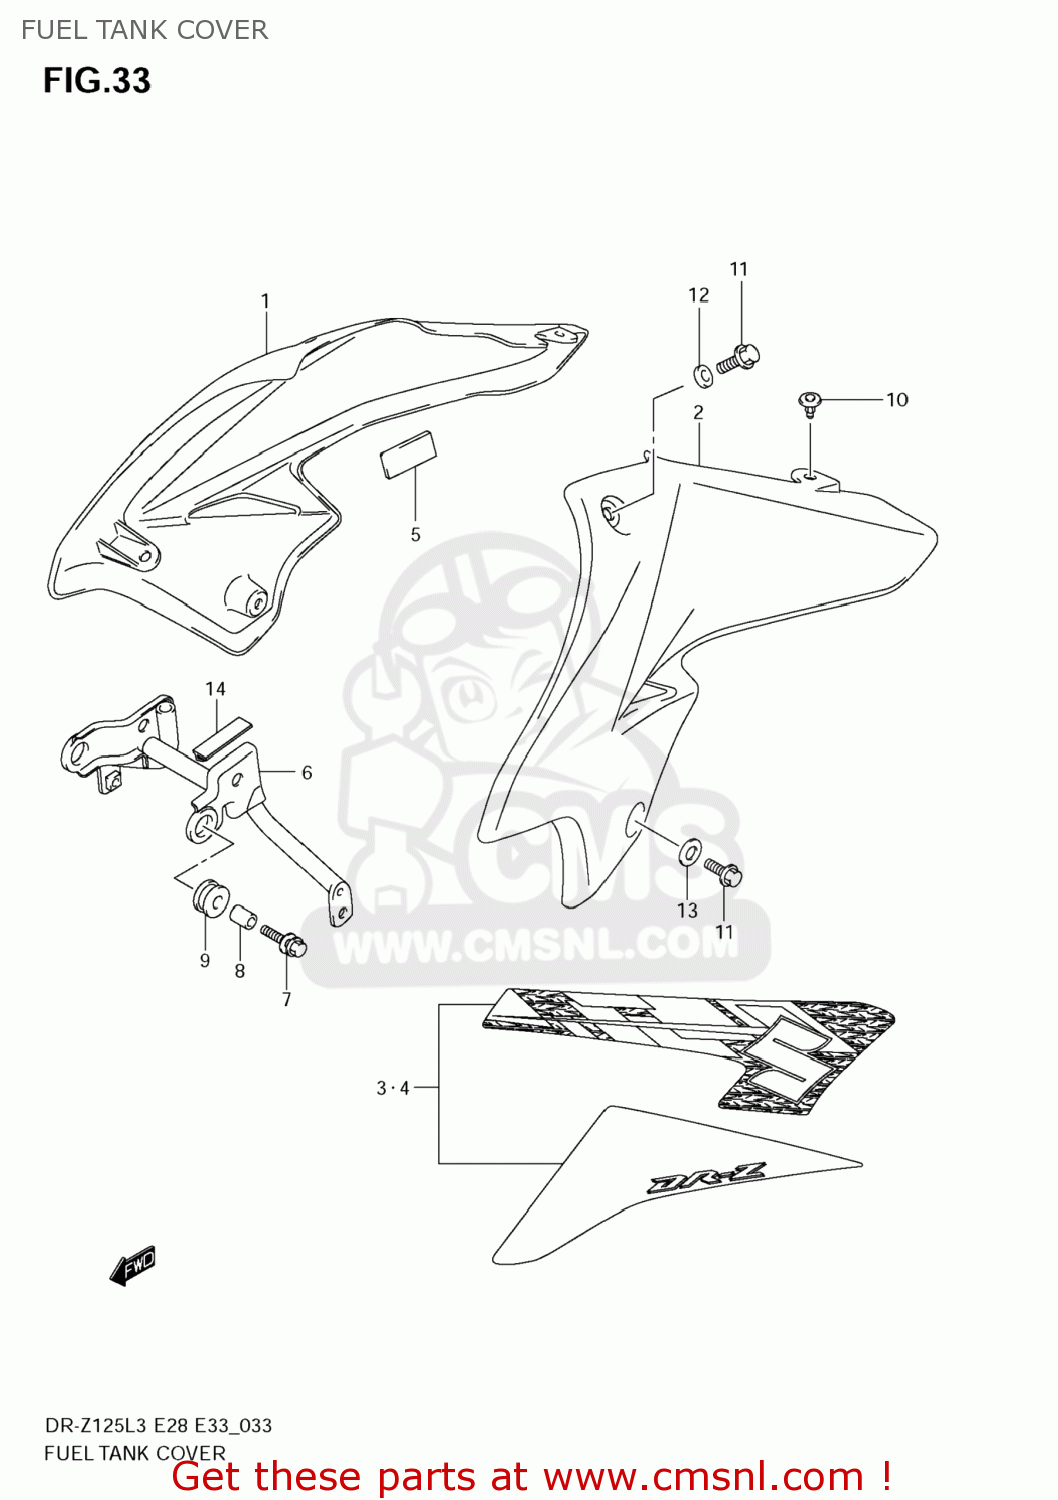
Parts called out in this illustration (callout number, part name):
1	COVER,FUEL TANK,R
2	COVER,FUEL TANK,L
3	TAPE SET,FUEL TANK COVER,R
4	TAPE SET,FUEL TANK COVER,L
5	CUSHION,FUEL TANK COVER
6	BRACKET,FUEL TANK FR
7	BOLT(6X25)
8	SPACER(6.5X9X13.5)
9	CUSHION,FUEL TANK SIDE
10	CLIP(BLACK)
11	BOLT
12	WASHER
13	WASHER
14	MOLDING
